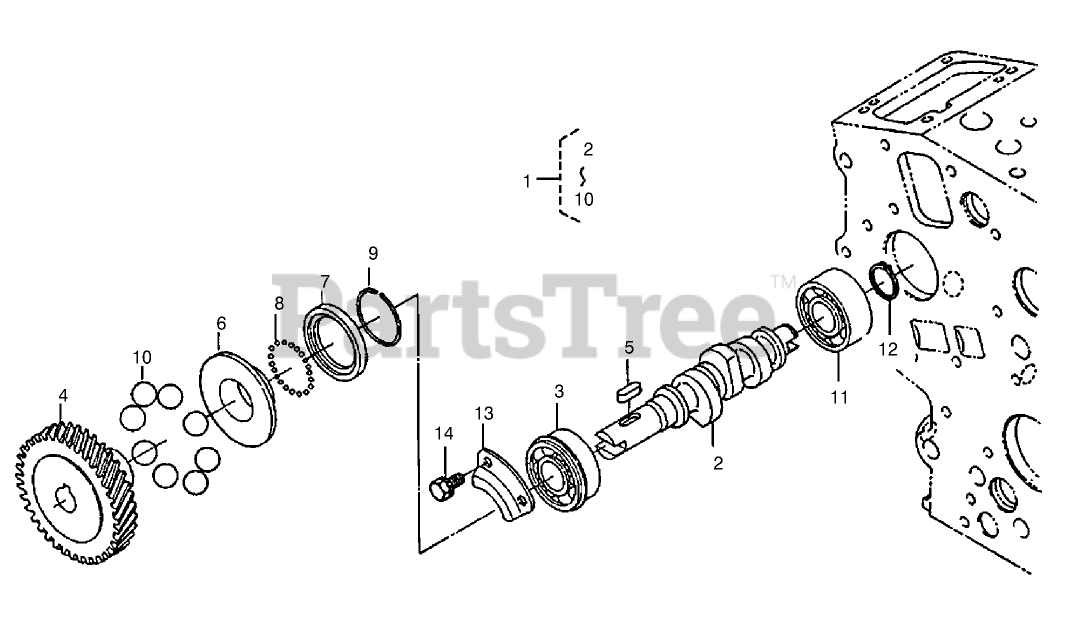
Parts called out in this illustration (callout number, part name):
1	FUEL CAMSHAFT ASM
2	CAMSHAFT
3	BEARING-BALL
4	GEAR-PUMP, INJECTION
5	KEY-FEATHER
6	SLEEVE-GOVERNOR
7	CASE-BALL, GOVERNOR
9	CIRC-CLIP
11	BEARING-BALL
12	CIRC-CLIP, EXTERNAL
13	STOPPER-FUEL, CAMSHAFT
